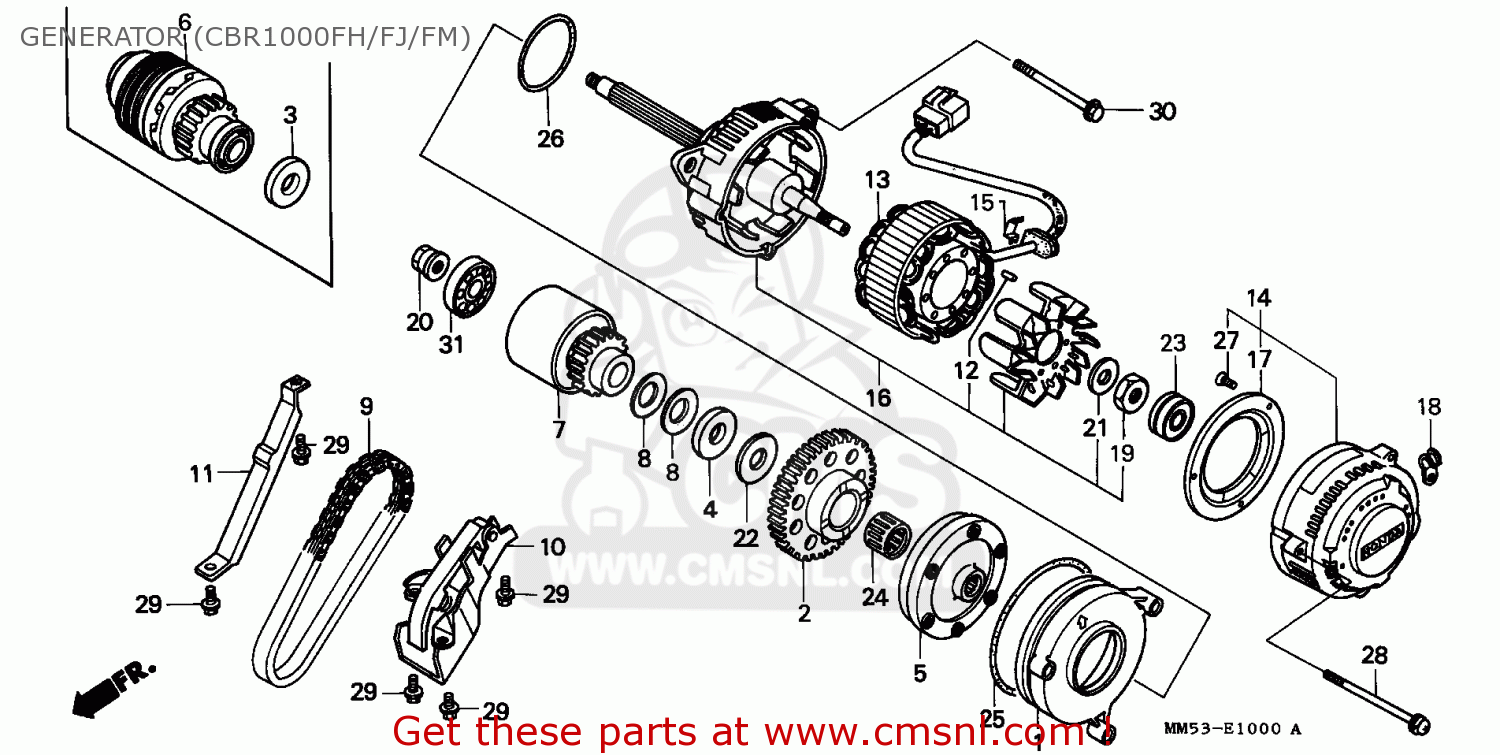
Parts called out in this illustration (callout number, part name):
1	BASE,ACG
2	GEAR COMP.,STARTI
3	COLLAR,GENERETOR
5	OUTER COMP.,START
6	ACG DAMPER ASSY
9	CHAIN,A.C.GENERAT
10	TENSIONER ASSY,AC
11	GUIDE,ACG CHAIN
12	PIN,GEN.A.C
13	STATOR.COMP
14	COVER.A,A,C GEN
15	CLIP,GROMMET
16	CASE.GEN.A.C,
17	COVER,FAN
18	CLAMP.CORD
19	NUT,LOCK ROTOR
20	NUT,FLANGE,12MM
21	WASHER,25X15.2X1
22	WASHER,20X37X2
23	B/BRG RAD N/COM
24	NEEDLE BRG
25	O RING, 104X2.2
26	O-RING
27	SCREW-WASHER,4X8
28	SCREW-WASHER,5X77
29	BOLT,FLANGE,6X14
30	BOLT,FLANGE,8X45
31	B/BRG RAD N/COM
